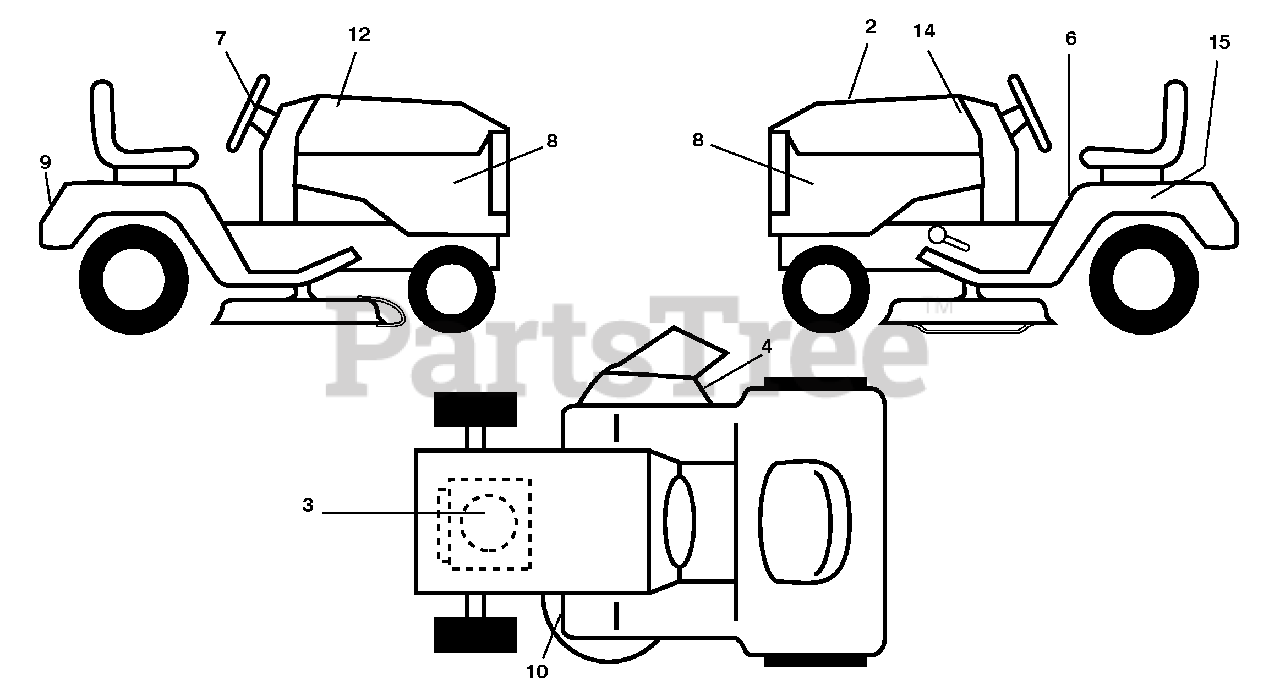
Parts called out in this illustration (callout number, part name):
2	Decal, Replacement
3	Decal, Engine HP
4	Decal, Warning
6	Decal, Fender Warning (E&F)
7	Decal, Ins Str Wh
8	Decal, Side Panel
9	Decal, Fender
10	Decal, V-Belt Sch.
12	Decal, Hood RH
14	Decal, Hood LH
15	Decal, Caution, Battery
15	Decal, Handle Lft Height Adj.
15	Manual, Operator's, English & French
15	Manual, Parts, English & French
